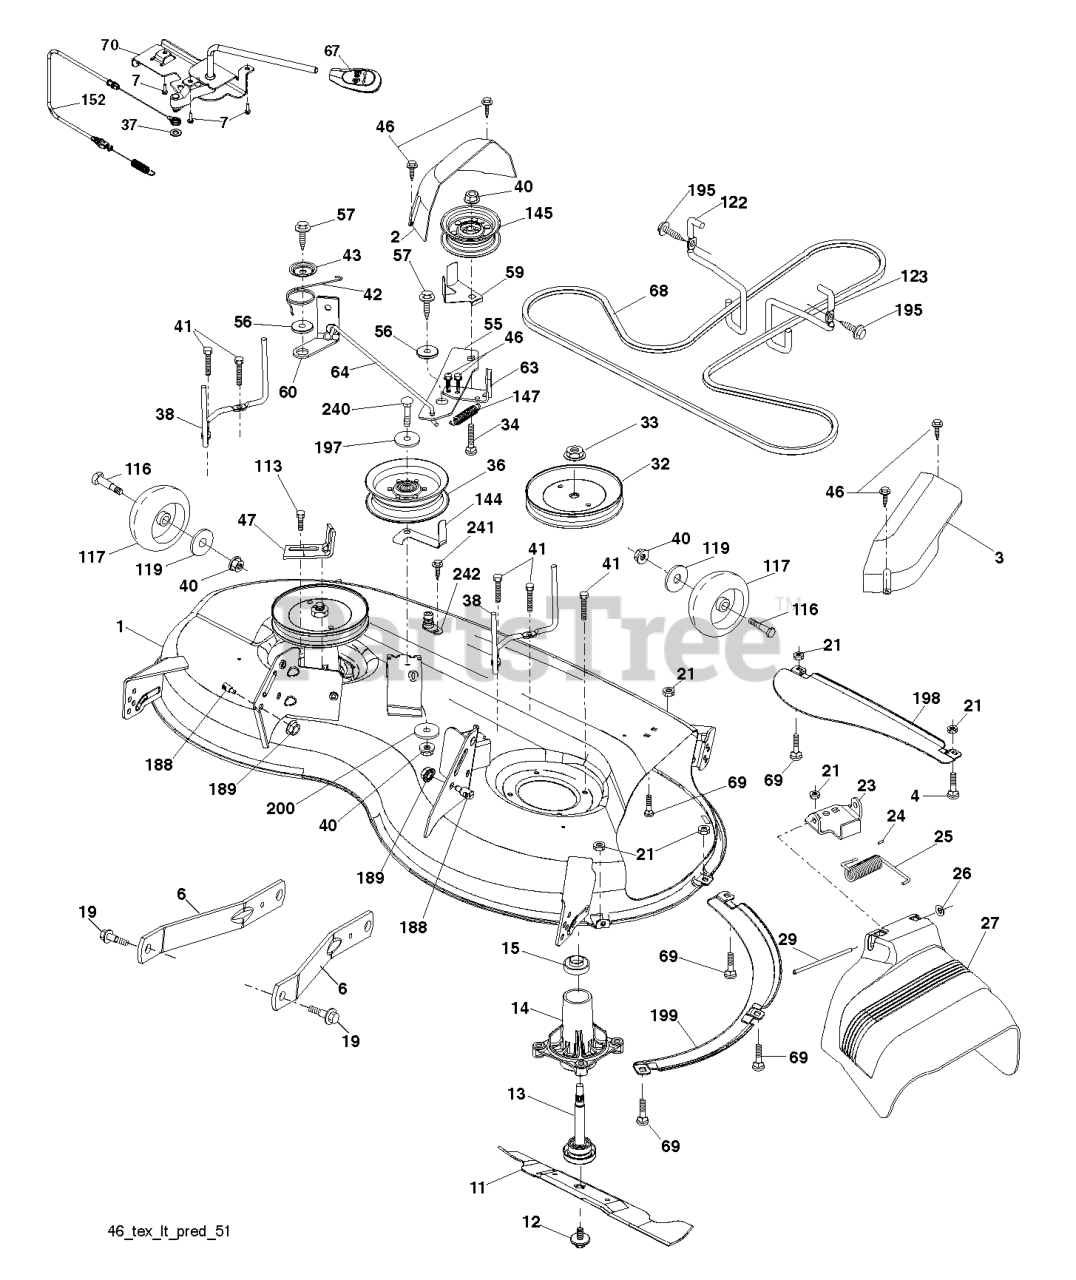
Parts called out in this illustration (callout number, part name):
1	HCS 5/16C X 3/4
2	COVER 46 XFAB TRACTOR LH MANDR
3	COVER 46 XFAB TRACTOR RH MANDR
4	Bolt, Hex Head 5/16-18 UNC x 3/4 (AYP part number)
6	ARM.SUSPENSION.MOWER.R
7	SCREW.#10 X 0.750.BOS (2 2)
11	BLADE.MOWER.46".HI.LIFT
12	SCREW.SEMS.7/16-20X1.HEX.HEAD
13	SHAFT ASM.MNDRL.N/GREASEABLE
14	HOUSING.MANDREL.4PT.
15	BEARING.MANDREL.TOP.EXTENDED
19	BOLT.SHOULDER
21	Locknut, Hex w/Insert 5/16-18 Unc
23	BRKT.DEFLECTOR.38"2005+
24	Cap Sleeve 80x 112 Blk Mower (AYP part number)
25	SPRING.TORSION.DEFLECT
26	Nut Push Phos & Oil (AYP part number)
27	SHIELD.DEFLECTOR.MOWER.46"BLAC
29	Rod Hinge 42" 6 75 Wlg (AYP part number)
32	PULLEY.MANDREL.5.438.PD
33	NUT.FLANGE.LOCK.TOP
34	Bolt Carriage 3/8-16 x 1-1/2 (AYP part number)
36	PULLEY.IDLER.2006
37	Washer 13/32 x 1-3/16 x 12 Gauge (AYP part number)
38	KEEPER.BELT.MANDREL.PULLEY
40	NUT LOCK FLG 3/8-16 UNC
41	BOLT.HEX.WASHR.HED.313-18X1.19
42	SPRING.TORSION.BRAKE
43	SRPING.TORSION.RETAINE
46	Screw Hex Thd Cut 1/4-20x5/8 T (AYP part number)
47	BRKT.CLUTCH.CABLE
55	IDLER.ARM
56	SPACER.RETAINER
57	SCREW 3/8-16X1
59	Guard TUV Idler (AYP part number)
60	ARM BRAKE MOWER RH 38"
63	ARM BRAKE MOWER
64	LINKAGE BRAKE
67	HANDLE.CLUTCH.CABLE.LT
68	V-BELT
69	Bolt, Carriage 5/16-18 UNC x 5/8 (AYP part number)
70	CLUTCH.ASM.MANUAL.YT.PREDATORQ
113	BOLT.5/16HEX.WHS.HD
116	BOLT.SHOULDER.3/8-16X3-5/8.
117	WHEEL.GAUGE.RALLY
119	Washer 3/8 x 7/8 x 14 Ga. (AYP part number)
122	KEEPER BELT ENGINE LH
123	KEEPER BELT RH
144	KEEPER.BELT.MOWER
145	PULLEY.IDLER.48"PRIMARY
147	SPRING RETURN
152	CABLE.MECHANICAL.CLUTCH
188	STUD.FASTNER.W/ANTI-ROTATE
189	NUT LOCK HEX FLANGE 5/16-18
195	SCREW, 3/8-16X3/4
197	Washer 13/32 x 13/16 x 12 Gauge (AYP part number)
198	BAFFLE CENTER FRONT
199	BAFFLE FRONT RH
200	WASHER.13/32 X 1 X 1/2.11GUARD
240	BOLT-HEX EAK
241	SCREW.TT.#10-32X.5.3/8.FLANGE
242	PORT.WASHOUT
